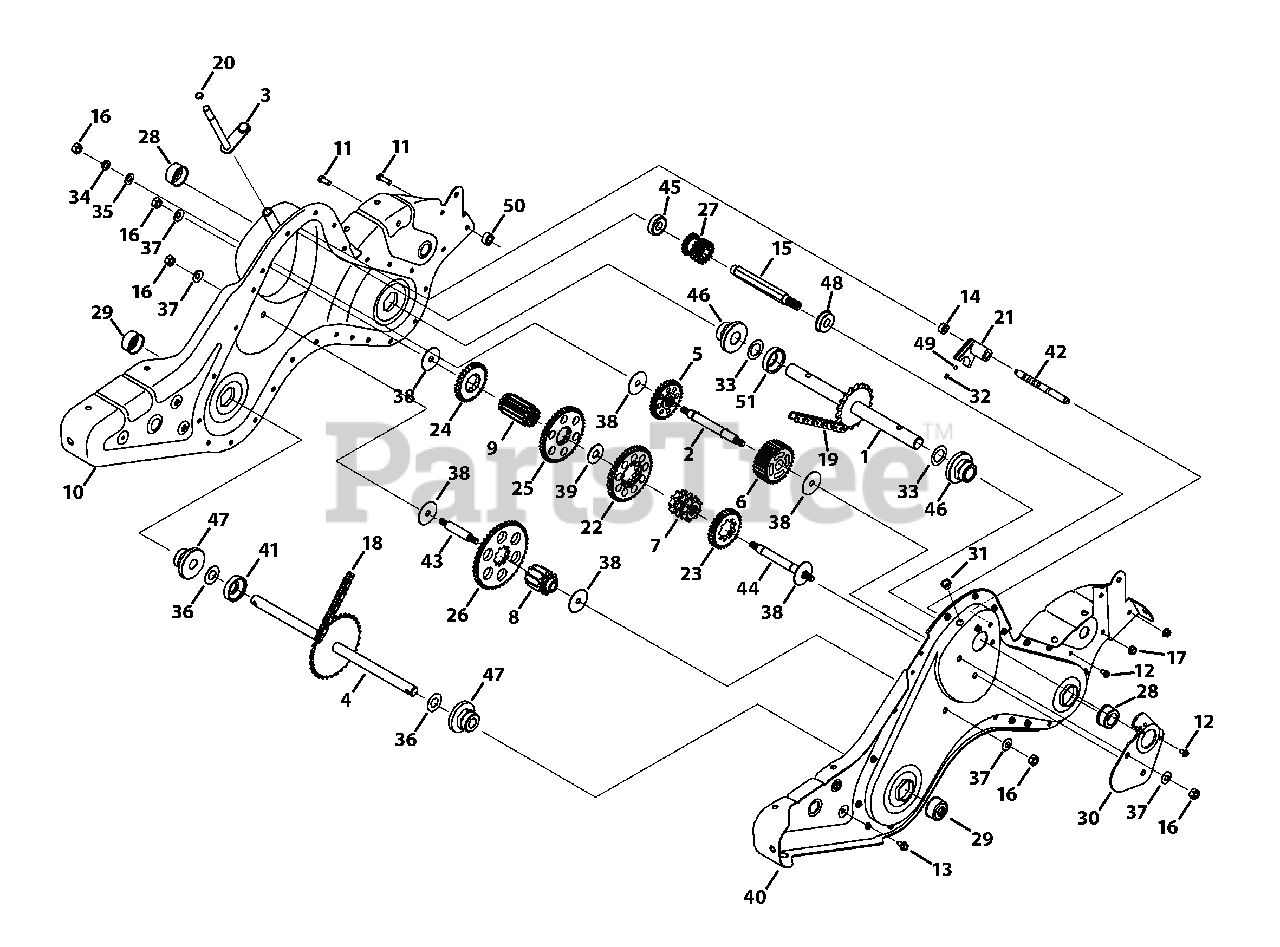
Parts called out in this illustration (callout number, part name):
1	Shaft Assembly, Tine, 18T
2	Shaft Assembly, Jack
3	Shaft Assembly, Shift Input
4	Shaft Assembly, Wheel, 33T
5	Gear Assembly, 30T Reverse Idler
6	Gear Assembly, 30T Tine Idler
7	Sprocket Assembly, 9T Tine Input
8	Sprocket Assembly, 10T Whl Input
9	Gear Assembly, 11T
10	RH Chain Case Housing Assembly
11	Hex Head Screw, 5/16-18 x 1.00
12	Screw, 1/4-20 x 0.625
13	Screw, :5/16-18 x 0.75
14	Spacer, .505 ID x .88 OD x .440
15	Input Shaft, .75
16	Nut, Hex, 7/16-20
17	Nut, Flangelock, 5/16-18
18	Endless Chain, #420 x 50 Links
19	Endless Chain, #50 x 54 Links
20	Snap Ring, .500
21	Clutch Collar
22	Gear Spur, 44T
23	Gear Spur, 30T
24	Gear Spur, 30T
25	Gear Spur, 44T
26	Gear Spur, 44T
27	Gear Spur, 16T
28	Shaft Seal, 1.0
29	Shaft Seal, .75
30	Positioner Gear Bracket
31	Tapered Cap Plug
32	Compression Spring, .230 OD
33	Washer, Flat, 1.03 x 1.62 x .03
34	Washer, Lock, 7/16
35	Washer, Flat,.474 x .879 x .064
36	Washer, Flat, .760 ID x 1.50 OD
37	Washer, Bell,.45 x 1.00 x .062
38	Washer, Thrust, .445 x 1.92 x .060
39	Washer, Flat,1.595 x .635 x .062
40	LH Chain Case Housing
41	Spacer, .75 x 2.0 x .50
42	Shaft Detent, .5 DIA
43	Shaft, Jack, .625 x 2.385
44	Shaft, Jack, .6250 x 5.0050
45	Ball Bearing, 17 x 40 x 12:6203
46	Flange Bearing, 1.0 x 2.5 x 1.38
47	Flange Bearing, .75 x 2.5 x 1.38
48	Ball Bearing, 17 x 40 x 12:6203
49	Ball, Detent, .250
50	Spacer, .315 x .750 x .375 LG
51	Spacer, 1.0 ID x 2.0 OD x.5 LG
